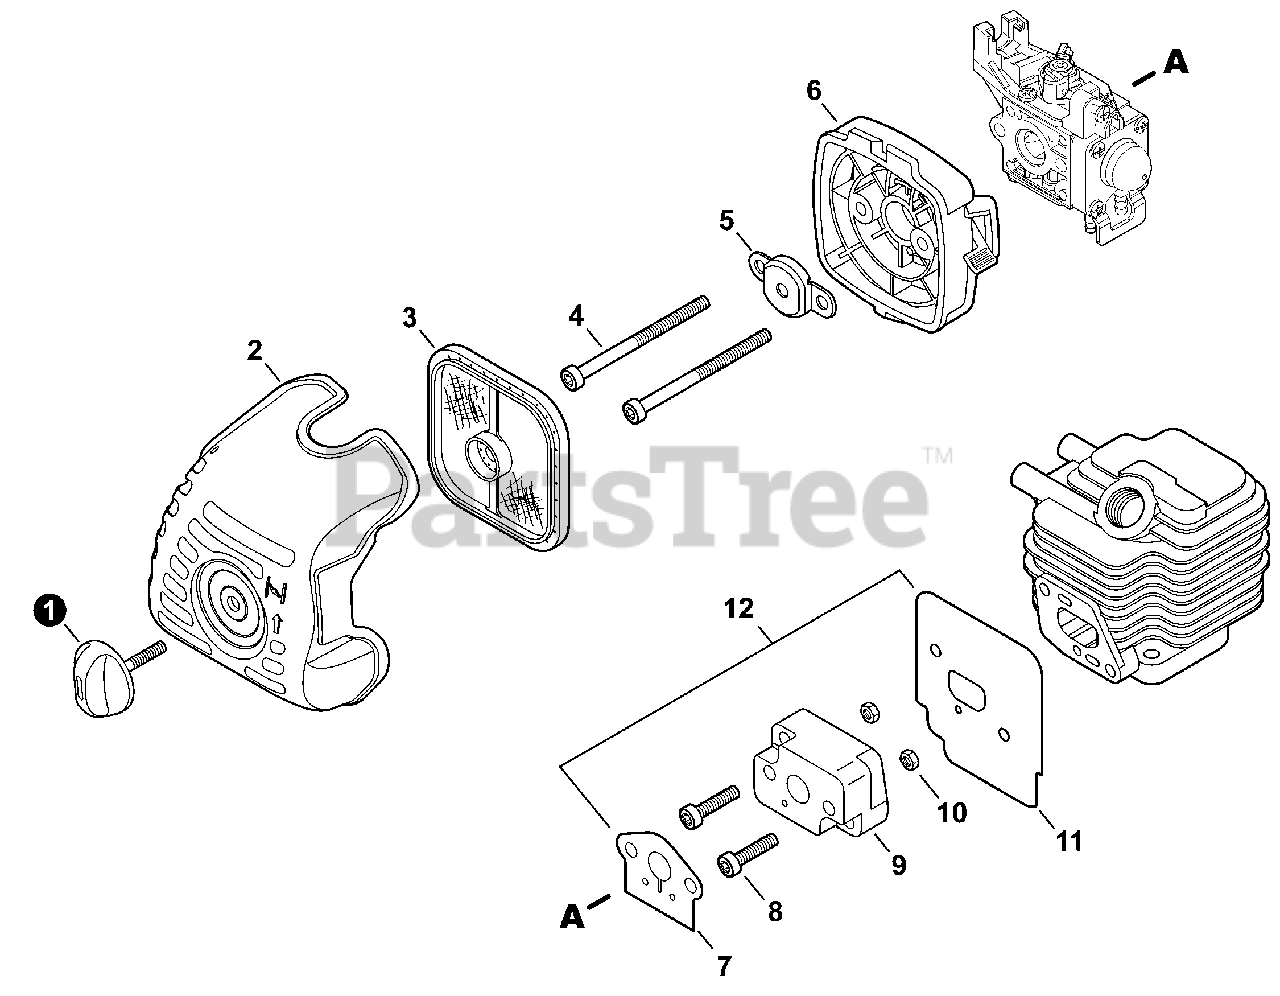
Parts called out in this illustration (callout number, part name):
1	THUMBSCREW
2	COVER, AIR FILTER
3	FILTER, AIR - DOUBLE LAYER
4	BOLT, TORX 5×65
5	PLATE, PREVENT
6	CASE ASSY, AIR FILTER
7	GASKET, INTAKE
8	BOLT, TORX 5×20
9	INSULATOR, INTAKE
11	HEAT SHIELD, INTAKE
12	GASKET KIT
